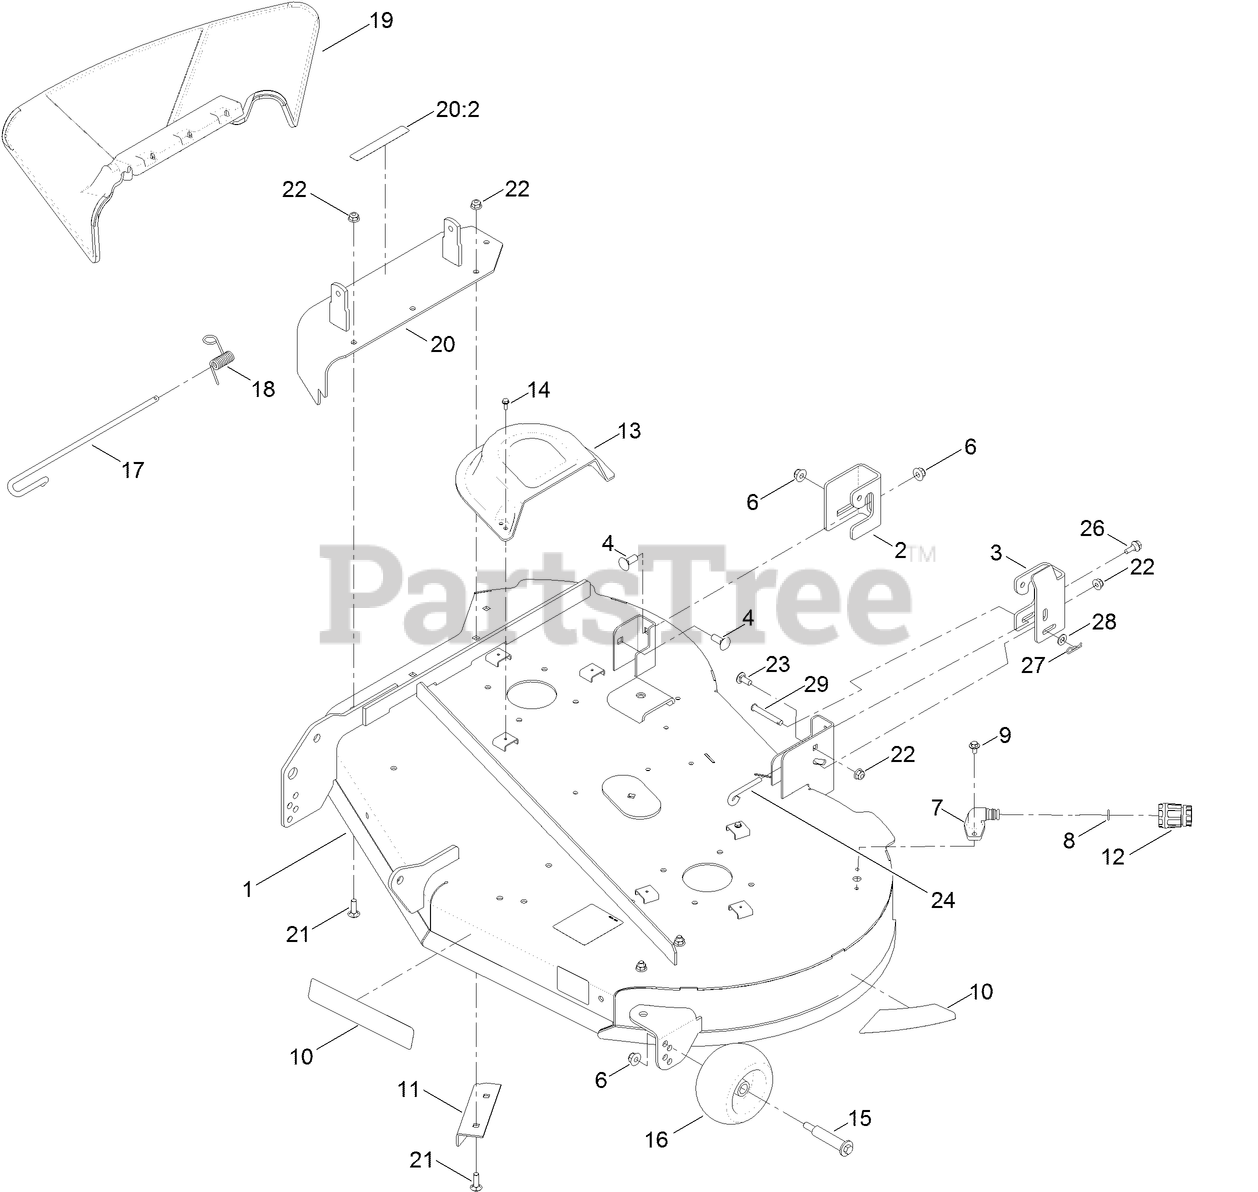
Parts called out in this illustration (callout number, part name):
1	42 IN DECK AND DECAL ASM
2	BRACKET-HANGER, RH
3	BRACKET-HANGER, LH
4	BOLT-CARR
6	NUT-HF, NI
8	O-RING
9	SCREW-HHFTF
10	DECAL-DECK
11	BAFFLE-CUTOFF
12	CONNECTOR-HOSE
13	COVER-BELT
14	SCREW-TAPTITE
15	BOLT-SHOULDER
16	ROLLER-SCALP, ANTI
17	PIN-CHUTE
18	SPRING-TORSION
19	DEFLECTOR-DISCHARGE
20	COVER ASM W/DECAL
20:2	DECAL-DANGER
21	SCREW-CARR
22	NUT-HF, NI
23	SCREW-CARR
24	ROD-LEVEL, DECK
26	SCREW-SHOULDER,HWH
27	PIN-COTTER
28	WASHER-PLAIN
29	PIN-CLEVIS
